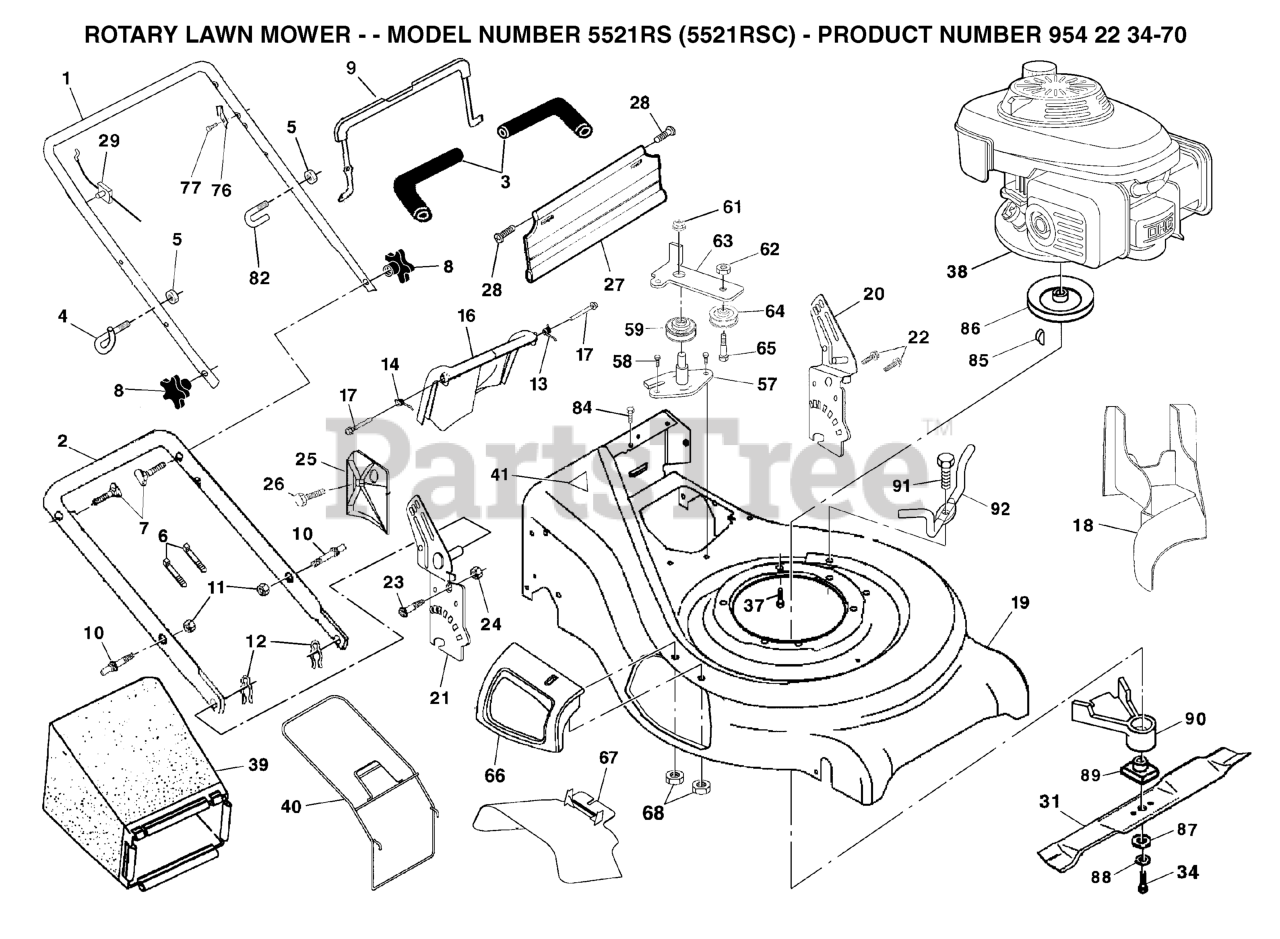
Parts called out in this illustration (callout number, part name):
2	HANDLE, LOWER
3	GRIP.HANDLE.FOAM.WIDE.(1 SIDE)
4	ROPE, GUIDE
5	NUT
6	TIE GUIDE
7	HANDLE BOLT
8	KNOB.HANDLE.STAR.HUSQ.GRAY
9	BAIL, FLAT AUTO WALK
11	NUT.CENTERLOCK.5/16-
12	HAIRPIN COTTER
13	SPRING.RH.REAR.DOOR.21.RWGD
14	SPRING.LH.REAR.DOOR.21.RWGD
16	DOOR.REAR.PLASTIC.21.RWGD.BLAC
18	PLUG, MULCHER
22	SELF-TAPPING SCREW 5/16-18X3/4
23	BOLT, HEX HEAD 5/16-18
24	NUT.71038.31-18.HEX.NYLOCK
25	CLIPPING DEFLECTOR
28	HINGE SCREW
29	ENGINE ZONE CONTROL CABLE
31	BLADE.21.PUSH/RWGD/FWG
34	SCREW, HEX HD 3/8-24 X 1-3/8
37	BOLT 3/8-16X1-1/8
40	GRASS CATCHER FRAME
41	DECAL HYT
57	BRACKET ASSEMBLY
59	PULLEY ASSY
61	NUT
62	LOCKNUT
63	IDLER ARM
64	IDLER PULLEY
65	SHOULDER BOLT
66	MULCHER DOOR ASM.
67	DEFLECTOR, DISCHARGE
76	BRACKET UPSTOP
85	HI-PRO KEY
86	PULLEY.ENG.25MMM
87	WASHER,HARDEN
88	LOCKWASHER
89	BLADE ADAPTER
90	DEBRIS SHEILD
91	SCREW
92	BRACKET
